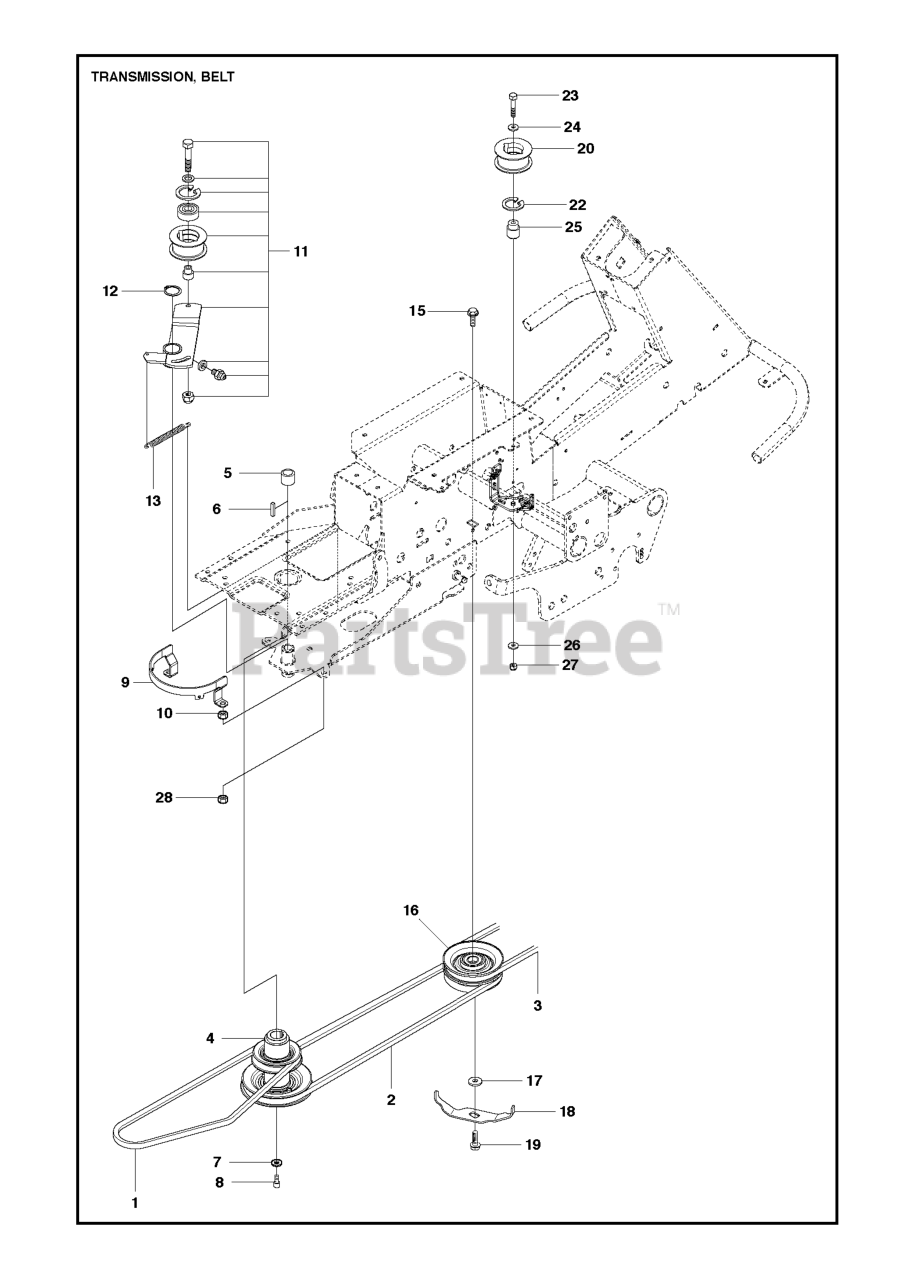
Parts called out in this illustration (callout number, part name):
1	BELT
9	BELT GUIDE
10	NUT
12	RETAINING RING SGA 25
16	PULLEY
17	WASHER
18	BELT GUIDE
19	BOLT
20	BELT TENSIONER WHEEL ASSY
22	RETAINING RING
26	WASHER BRB 8.4X17
27	LOCKNUT M8
28	Screw M10x25
